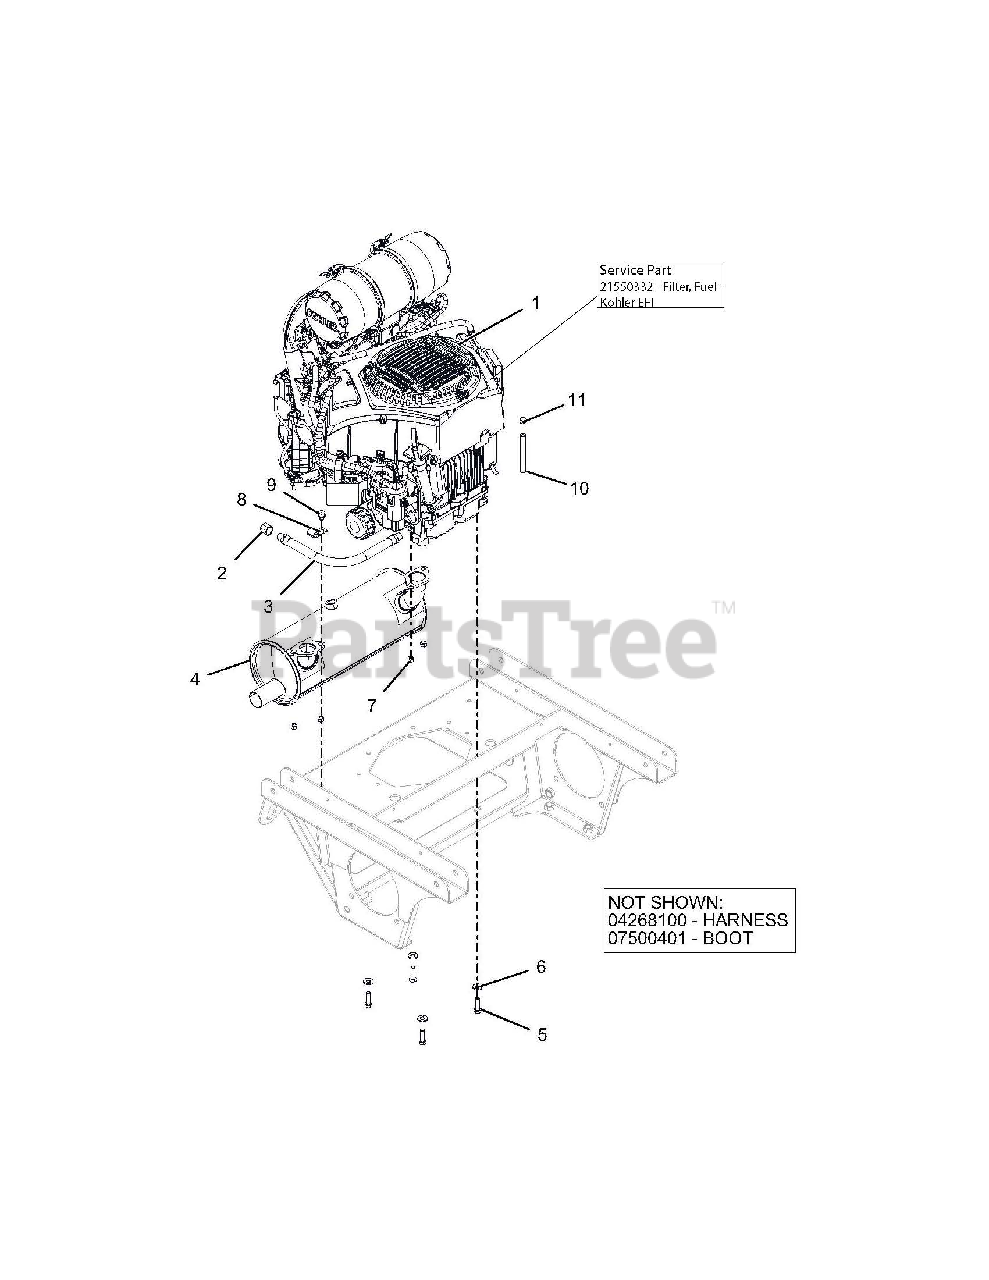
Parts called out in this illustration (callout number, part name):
1	ENGINE, KOHLER EFI
1	FILTER, FUEL - KOHLER EFI
2	PIPE, CAP 3/8 NPT FEMALE
3	HOSE, HYD .38-11-OK M6N0-M6N0
4	MUFFLER, KOHLER EFI
5	BLT-HEX .38-16X1.25 GR5 YWZC NYTORQ
6	WSHR, 3/8" SPRING DISC
7	NUT-LK-TOP M8-1.25 YWZC
9	SCR-TAP .38-16X.50 HWH TR YWZ
10	.25 LOW-PERM GAS HOSE 19.0" LG - VALVE TO ENGINE
11	CLAMP, FUEL LINE
